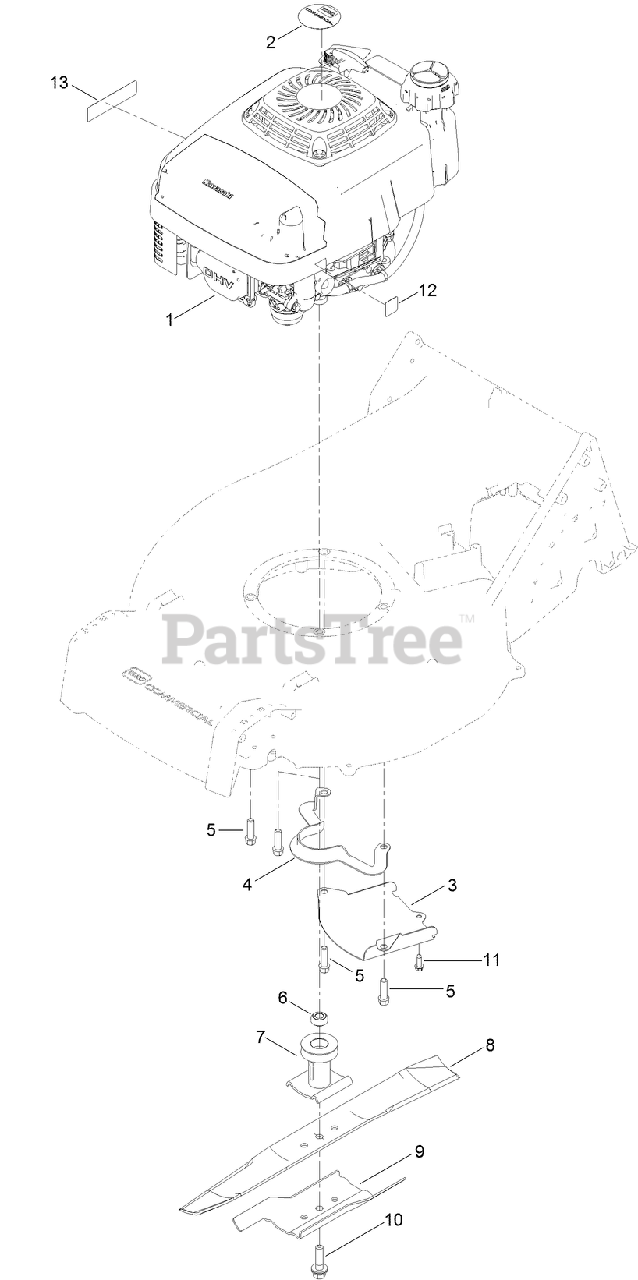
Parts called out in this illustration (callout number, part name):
1	ENGINE-KAWASAKI, FJ180V
3	SHIELD-GRASS
4	GUIDE-BELT
5	SCREW-TAPTITE
6	SPACER-DRIVER, BLADE
7	DRIVER-BLADE
8	BLADE-21IN, RECYCLING
9	ACCELERATOR-BLADE
10	BOLT-BLADE
11	SCREW-HWHTF
12	DECAL-PRIMER
13	DECAL-ARRESTOR, SPARK
